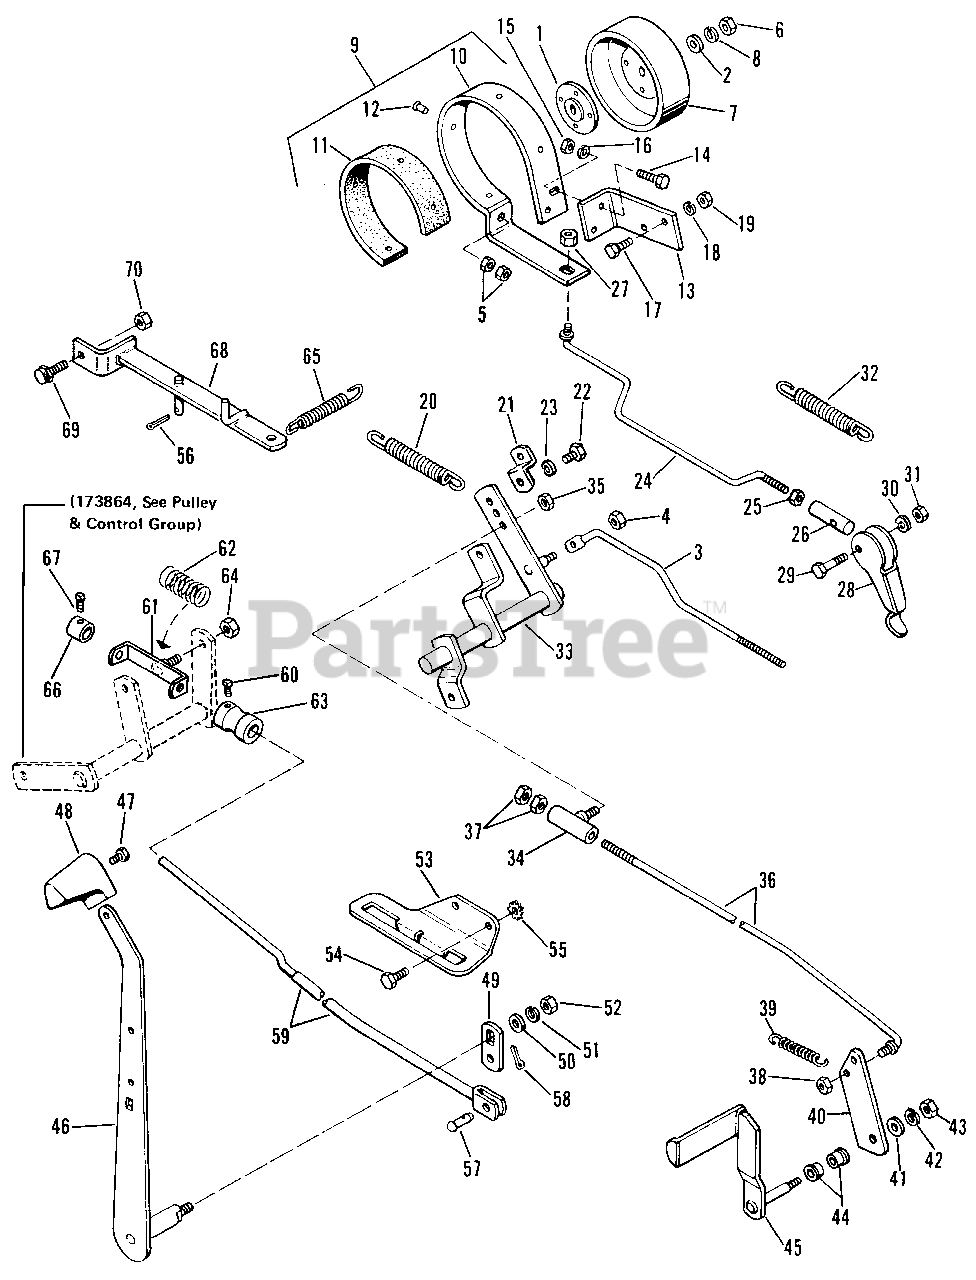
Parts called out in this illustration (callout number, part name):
1	Special Washer
2	Plain Washer, 3/8"
3	Brake Rod
4	Full Hex Nut, 5/16"-18
5	Full Hex Nut, 3/8"-16
6	Full Hex Nut, 7/16"-14
7	Brake Drum
8	Lockwasher, 7/16"
9	Brake Band & Lining Assembly
11	Brake Lining
12	Rivet No. 7 x 5/16"
13	Brake Band Bracket
14	Hex Capscrew, 3/8"-16 x 1"
15	Full Hex Nut, 3/8"-16
16	Lockwasher, 3/8"
17	Hex Capscrew, 1/4"-20 x 3/4"
18	Lockwasher, 1/4"
19	Full Hex Nut, 1/4"-20
21	Spring Clip
22	Hex Capscrew, 7/16"-14 x 1-1/4"
23	Lockwasher, 5/16"
24	Parking Brake Rod Assembly
25	Full Hex Lock Nut, 5/16"-18
27	Full Hex Nut, 5/16"-18
28	Parking Brake Lever
29	Hex Capscrew, 1/4"-20 x 1-1/4"
30	Double Lockwasher, 1/4"
31	Full Hex Lock Nut, 1/4"-20
33	Pivot Lever Assembly
34	Guide Rod Assembly
35	Full Hex Lock Nut, 5/16"-18
36	Clutch & Brake Rod Assy.
37	Full Hex Nut, 5/16"-18
38	Full Hex Lock Nut, 5/16"-18
39	Tension Spring
40	Arm-Foot Pedal
41	Plain Washer, 3/8"
42	Lockwasher, 3/8"
43	Full Hex Nut, 3/8"-16
45	Foot Pedal Assembly
46	Variable Planetary Lever Assy.
47	Hex Self Forming Thread Screw, 1/4"-20 x 7/8"
50	Plain Washer, 3/8"
51	Lockwasher, 3/8"
52	Full Hex Nut, 3/8"-16
54	Special Screw
55	Lockwasher, Shakeproof, 5/16"
56	Cotter Pin, 3/32" x 3/4"
58	Cotter Pin, 3/32" x 3/4"
59	Rod Assembly
60	Sq. Hd. Set Screw, 1/4"-20 x 3/8" Grade 8
61	Rod Guide Assembly
63	Brake Detent
64	Full Hex Lock Nut, 3/8"-24
65	Tension Spring
66	Set Collar
67	Sq. Hd. Set Screw, 1/4"-20 x 3/8" Grade 8
68	Brake Lever Assembly
69	Brake Pad Assembly
70	Hex Jam Nut, 5/16"-18
